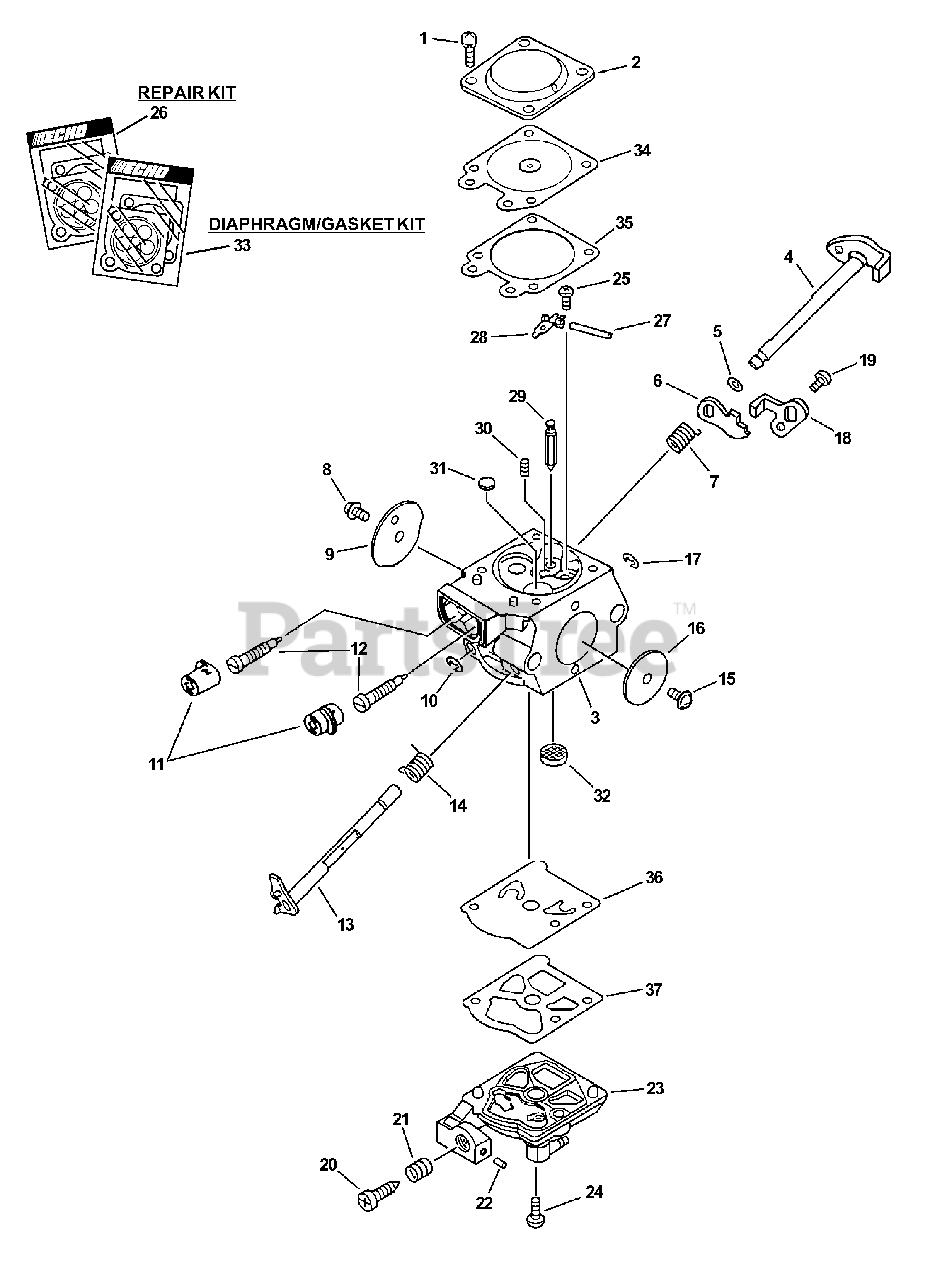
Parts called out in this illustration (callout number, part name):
2	COVER, METERING DIAPHRAGM
3	BODY, CARBURETOR
4	SHAFT, CHOKE
6	LEVER, FAST IDLE
7	SPRING, CHOKE RETURN
9	VALVE, CHOKE
11	CAP, LIMITER
12	NEEDLE, MIXTURE
13	SHAFT, THROTTLE
14	SPRING, THROTTLE RETURN
16	VALVE, THROTTLE
18	LEVER, THROTTLE
20	SCREW, IDLE ADJUST
21	SPRING, IDLE ADJUST
22	PLUG, FRICTION
23	COVER, FUEL PUMP
25	SCREW, METERING LEVER PIN
26	REPAIR KIT, CARBURETOR
27	PIN, METERING LEVER
28	LEVER, METERING
29	VALVE, INLET NEEDLE
30	SPRING, METERING LEVER
31	PLUG, WELCH
32	STRAINER
33	GASKET / DIAPHRAGM KIT
34	DIAPHRAGM, METERING
35	GASKET, METERING
36	DIAPHRAGM, PUMP
37	GASKET, PUMP
